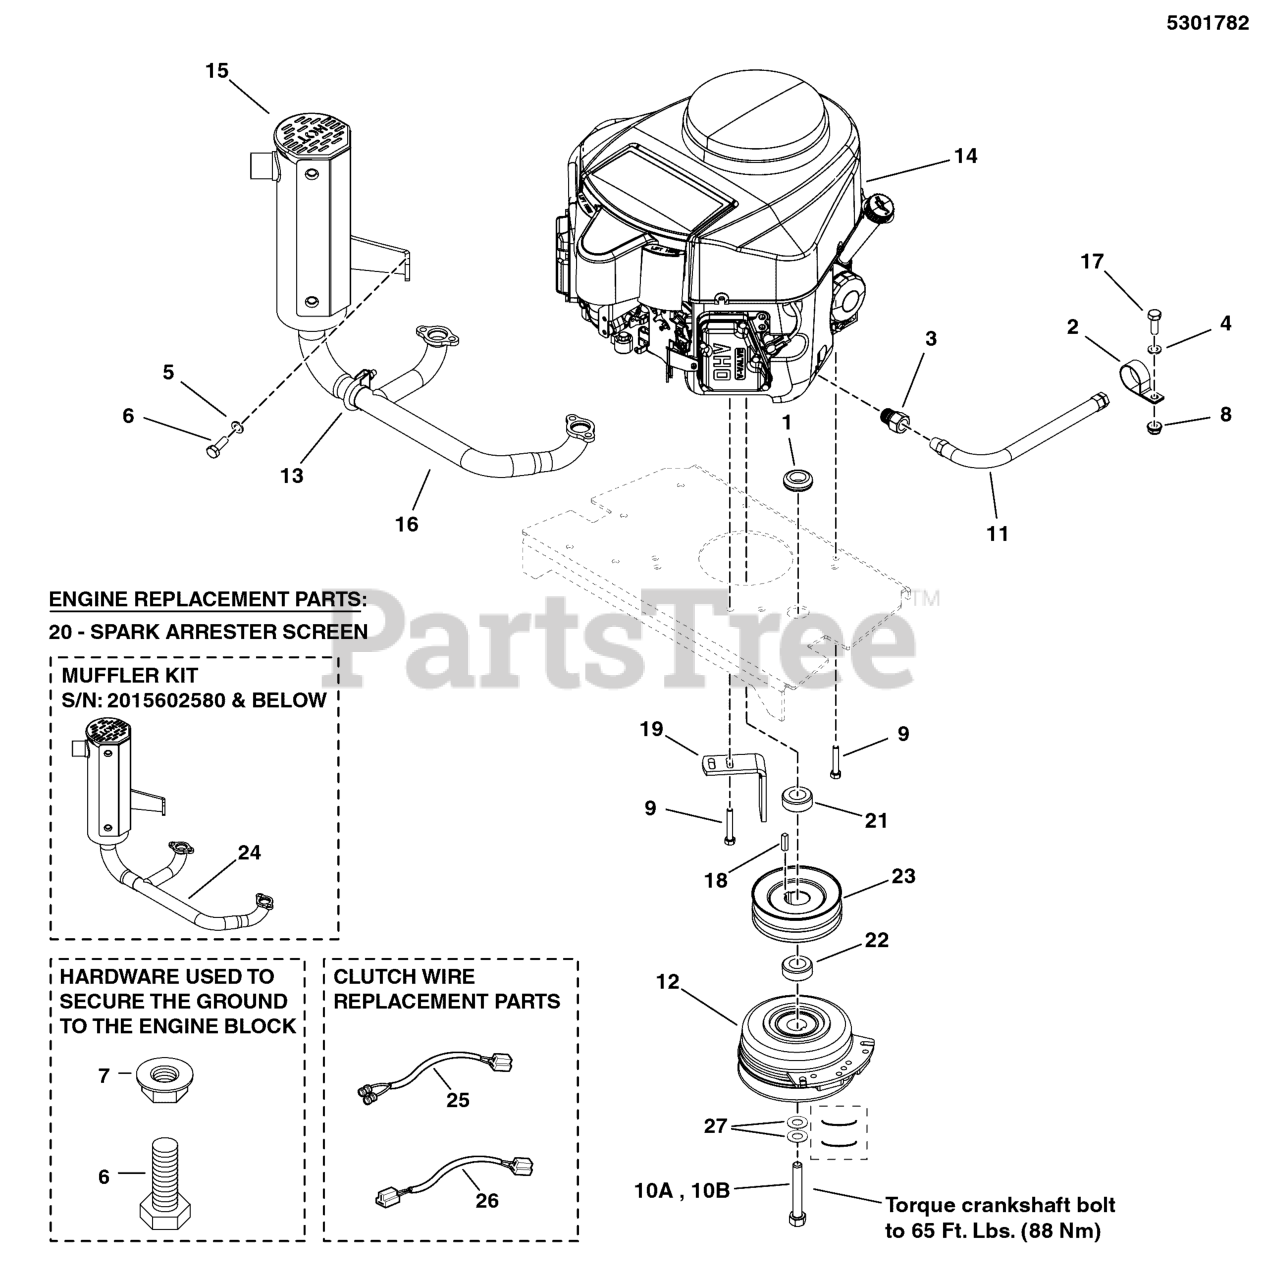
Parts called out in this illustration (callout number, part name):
1	GROMMET, 7/8
2	CLAMP, VINYL INSULATED
3	ADAPTER-OIL DRAIN
4	WASHER, 1/4 SAE
5	WASHER, 5/16" SAE
6	BOLT, M8-1.25 X 20MM GD8.8
7	NUT, M8-1.25 SERR. FLANGE, CZ
8	NUT, 1/4-20 HEX NYLOCK FLANGE
9	BOLT,HEX FLG, SER GD5 3/8-16X1-1/4,PATCH
11	HOSE, OIL DRAIN
12	* CLUTCH, 5218-134, WARNER
13	CLAMP, EXHAUST EXTENSION
14	ENGINE, KAWASAKI
15	MUFFLER, KAWASAKI, VERTICAL
16	MANIFOLD, KAWASAKI, VERTICAL
17	BOLT, 1/4-20 X 3/4 GD5 YZ
18	KEY, 1/4 SQ X 1
19	ANCHOR, CLUTCH - BLK
20	SCREEN, SPARK ARRESTER (SV)
21	SPACER, 1.13 X 1.75 X 1.03
22	SPACER, 1.13 X 1.75 X .50
23	PULLEY, CRANKSHAFT, 1.126 ID X 4.75 OD
24	KIT, MUFFLER & MANIFOLD
25	KIT, CLUTCH WIRE
26	WIRE HARNESS, JUMPER, WARNER CLUTCH
27	BELLEVILLE WASHER 1.1875 X .442 X .089
